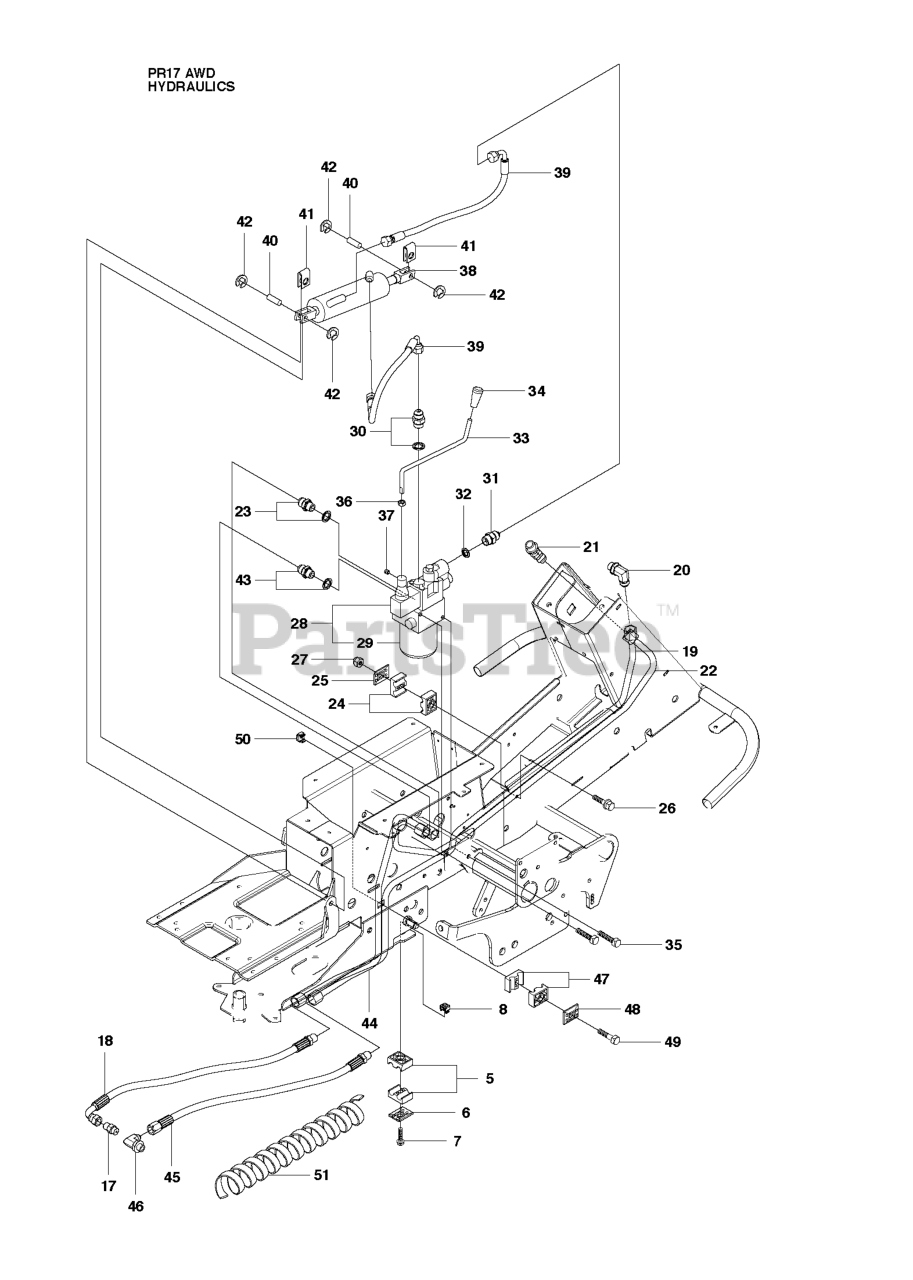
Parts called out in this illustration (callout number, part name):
5	PIPE CLAMP
6	COVER PLATE
7	SCREW EHHFM
24	PIPE CLAMP
27	LOCKNUT M6
29	FILTER
35	REPL BY 725 24 49-51
36	NUT
42	RETAINING RING SGA 10
47	PIPE CLAMP
51	HOSE GUARD D=43 L=400
